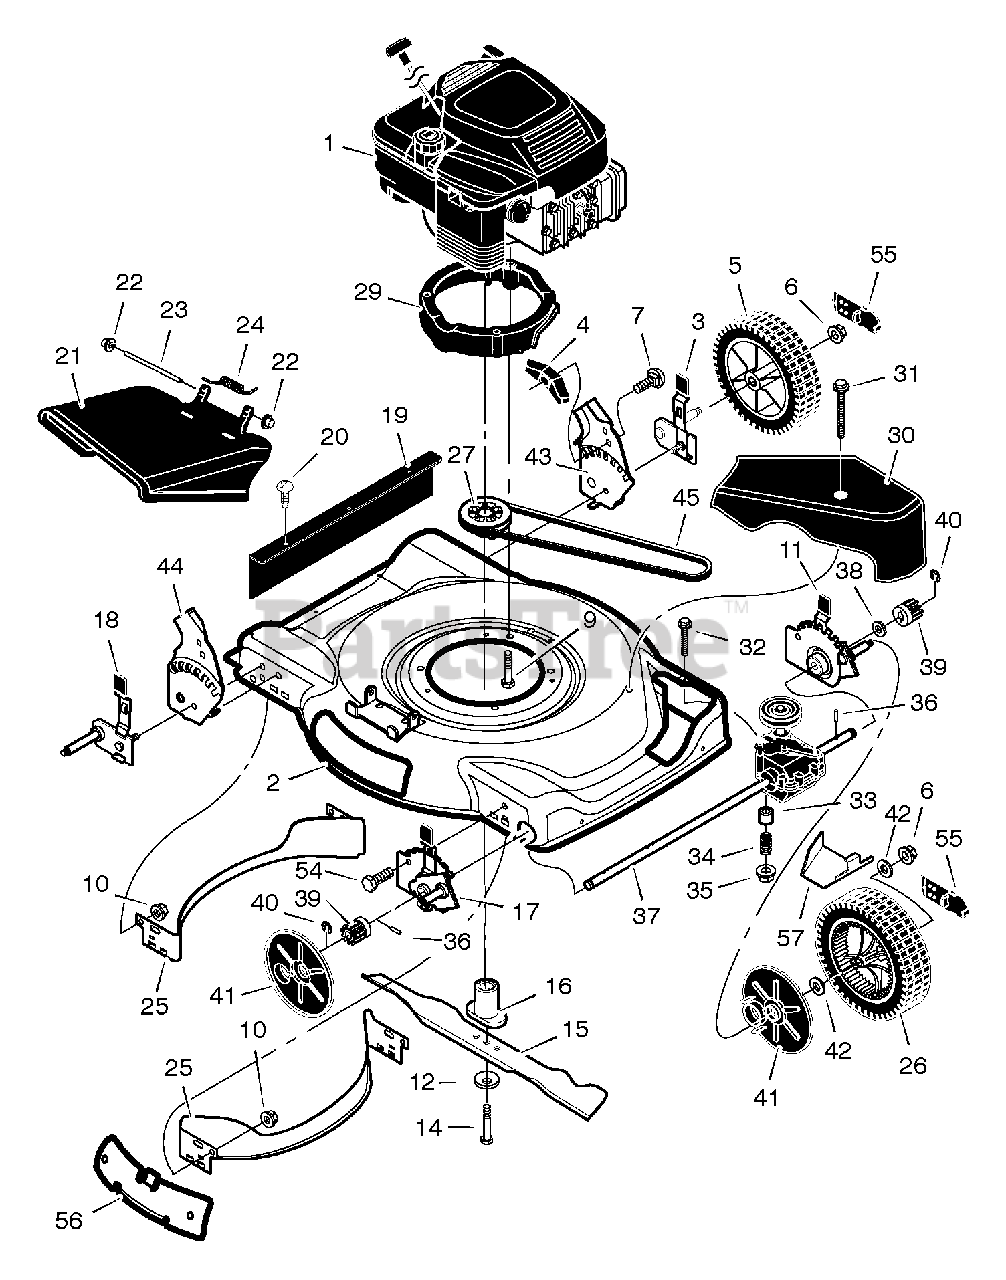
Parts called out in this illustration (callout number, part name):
1	Engine *
2	Housing
3	Height Adjuster, Left Rear
5	Wheel and Tire, Rear *
6	Locknut, Flange
7	Bolt, Carriage
9	Bolt, Engine
10	Nut
11	Height Adjuster, Left Front
12	Washer, Belleville
14	Bolt, Hex
15	Blade,
16	Adapter, Blade
17	Height, Adjuster, Right Frt.
18	Height, Adjuster, Right Rr.
19	Guard, Rear
21	Deflector, Chute
22	Push-On Cap
23	Pin, Pivot
26	Wheel and Tire, Drive *
28	Pin, Spring
29	Base, Engine
30	Cover, Belt (Black)
31	Screw
35	Nut
36	Pin, Drive
37	Transmission
39	Gear, Pinion
41	Cover, Dust
42	Washer
43	Bracket, Left Handle
44	Bracket, Right Handle
45	Belt, Briggs & Stratton
54	Bolt
55	Hub Cap
56	Plate, Mulch
57	Cover, Transmission
